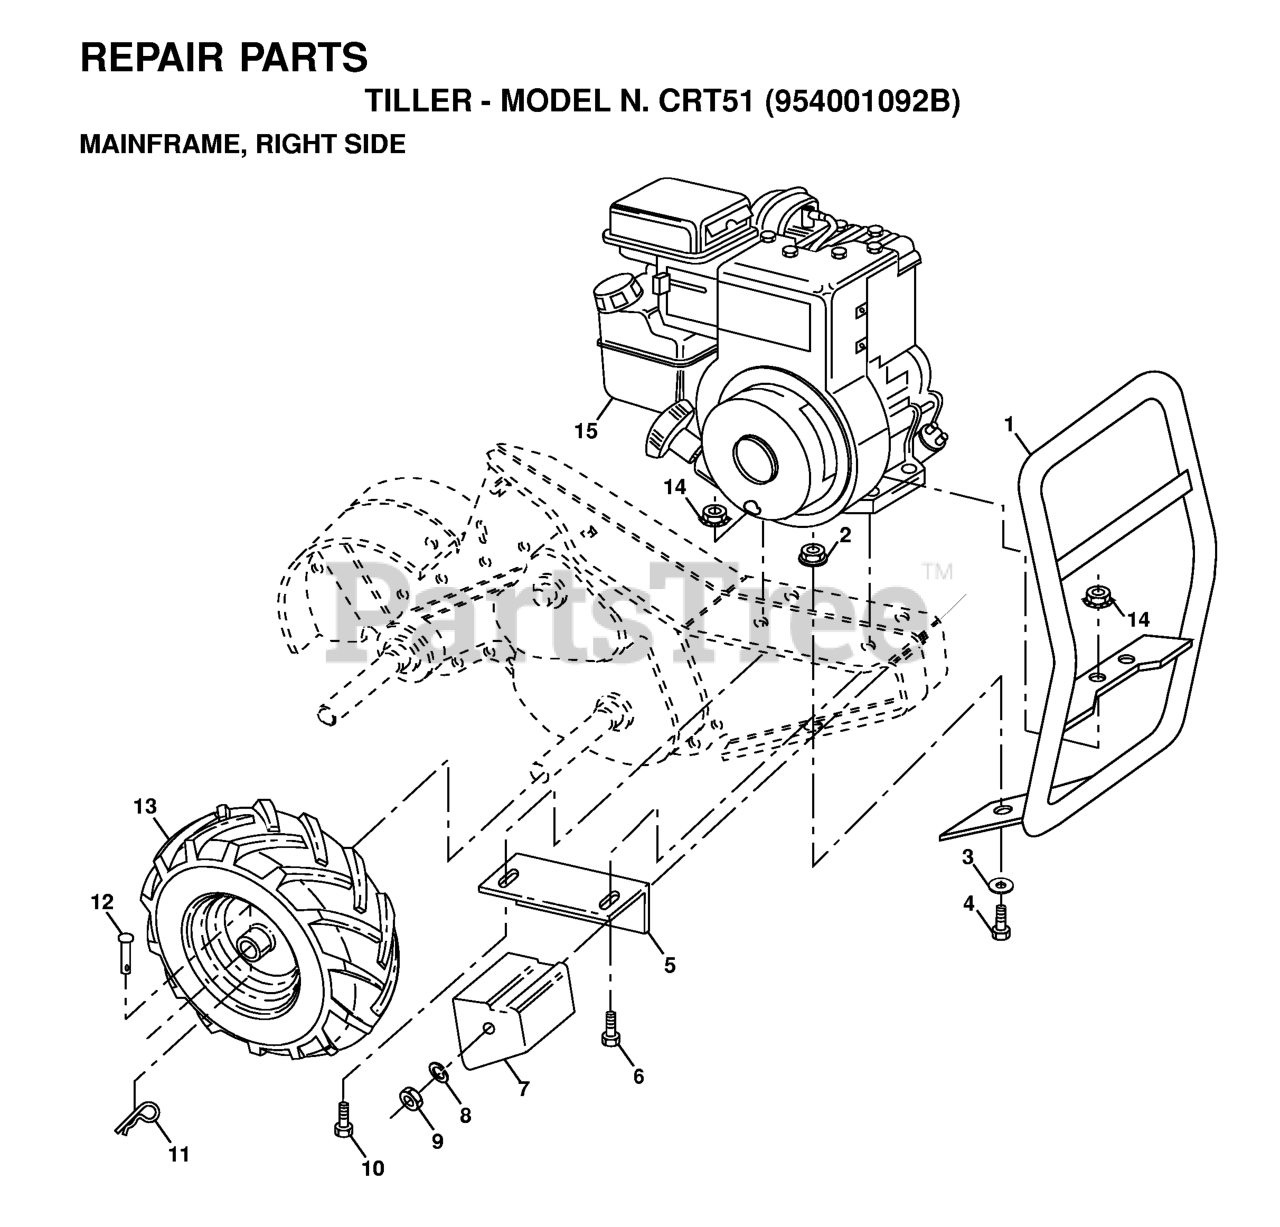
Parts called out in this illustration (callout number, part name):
1	BELT.V.IMPELLER
2	V-BELT.TRACTION.HYDRO.II.SNOW
3	ARM.IDLER BRAKE.CLEAR.ZINC
4	PULLEY.W/SPACER.2.75
5	BRACKET.IDLER.PIVOT.ZINC
6	NUT.FLANGE.HEX.5/16X18.BLACK
7	HEX BOLT
8	BOLT.SHOULDER.1/2X12
9	NUT.LOCK.5/16-18
10	BOLT.5/16HEX.WHS.HD
11	ARM.ASM.TRACTION.IDLER.
12	BOLT.BLADE
13	STEEL WASHER
14	WASHER, FLAT 3/8
15	PULLEY.IMPELER.
16	PULLEY,ENGINE TRACTION DRIVE
17	CAPSCREW.HEXHD.5/16X1.25.
18	WASHER.LOCK.HVY.HLCL.SPR.5/16
19	GUIDE.BELT.CHAIN.LS.SNOW
20	WASHER.20X8.5
21	RP BUSHING, IDLER PIVOT
22	SPACER.ENGINE.PULLEY
